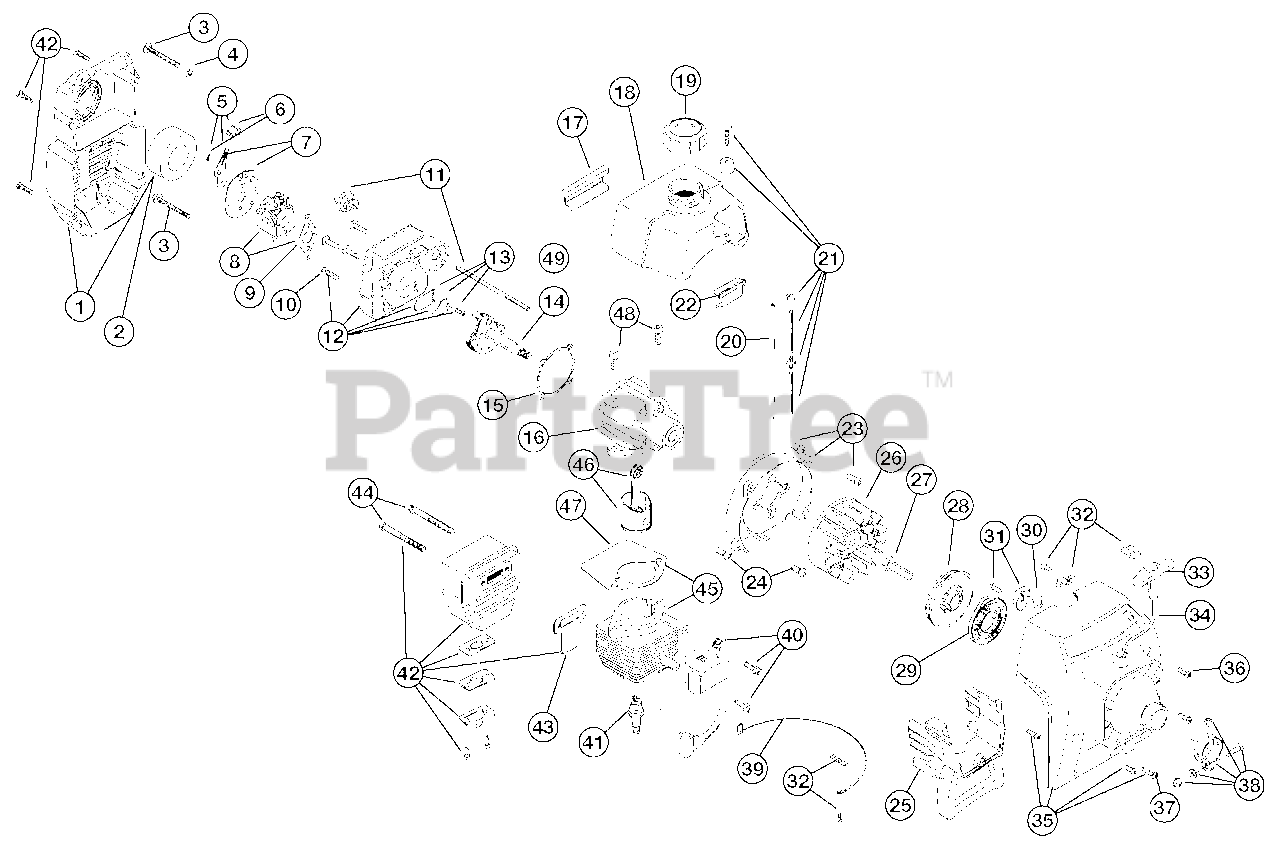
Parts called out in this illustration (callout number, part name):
1	Air Cleaner/Muffler Cover Assembly
2	Air Cleaner Filter
3	Carburetor Mounting Screw Assembly
4	Wavey Washer
5	Choke Lever Assembly
6	Choke Knob and Screw
7	Choke Lever and Plate
8	Carburetor Assembly
9	Carburetor Gasket
10	Carb Mount Screw
11	Primer and Hose Assembly
12	Carb Mount Assembly
13	Reed Assembly
14	Power Shaft Assembly
15	Crank Case Gasket
16	Crank Case Service Assembly
17	Rear Mounting Pad
18	Fuel Tank Assembly
19	Fuel Cap Assembly
20	Fuel Return Line
21	Fuel Line Assembly
22	Front Mounting Pad
23	Shroud Assembly
24	Shroud Screw
25	Shroud Extension and Stand
26	Flywheel Assembly
27	Square Nut Drive
28	Recoil Pulley Assembly
29	Recoil Spring
30	Rope Guide
31	Pulley Retainer Assembly
32	Switch Assembly
33	Pull Handle
35	Starter Housing Assembly
36	Housing Screw
37	Cover Screw
38	Upper Clamp Assembly
39	Wire Lead
40	Module Assembly
41	Spark Plug
42	Muffler Assembly
43	Exhaust Gasket
44	Muffler Mounting Bolt Assembly
45	Cylinder Assembly
46	Piston and Rod Assembly
47	Cylinder Gasket
48	Cylinder Bolt
